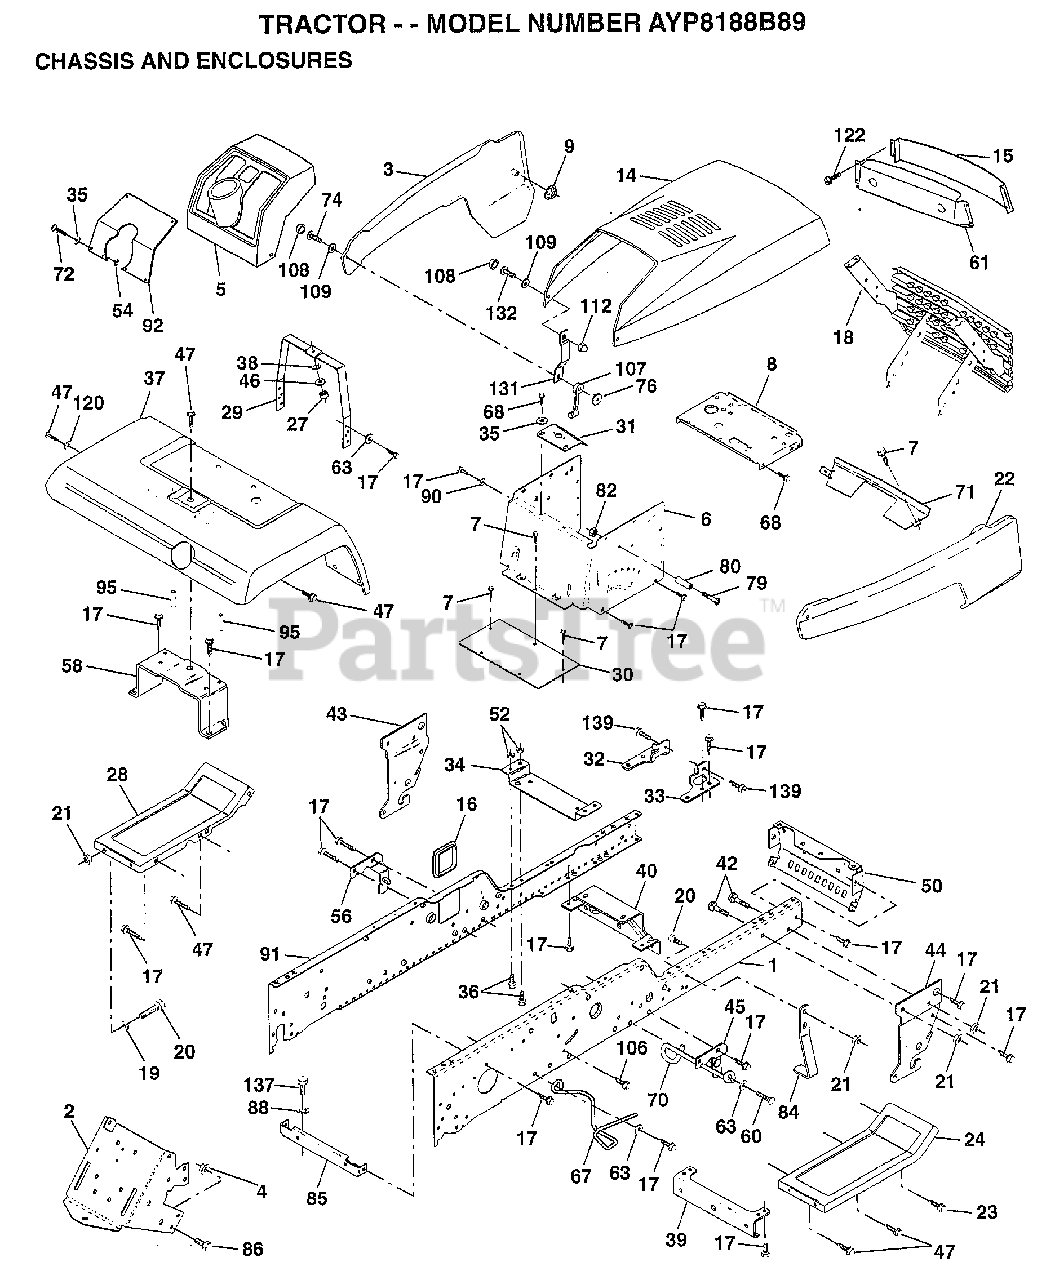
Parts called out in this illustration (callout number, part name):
1	"RAIL,FRAME RH"
2	DRAWBAR GT
3	"PANEL,ASM SIDE LH"
4	NUT.7/16
5	DASHBOARD BLACK
6	DASH LOWER
7	SCREW
8	SUPPORT.DASH.BTRY
9	PAL NUT LT
14	"HOOD ASM.,PNT"
15	LENS.BAR.CLEAR
16	COVER ACCESS
17	SCREW
19	WASHER
20	BOLT
22	PANEL ASM.SIDE RH
23	SCREW GTV
24	FOOTREST.RH.LT/GT
28	FOOTREST.LT.LT/GT
29	DASH.SUPT.YP/HUSQ
30	SADDLE.SCR.6SP
31	BRKT SUPT 1-PC VG
32	BKRT.PIVOT.CHASSIS.RH
33	BKRT.PIVOT.CHASSIS.LH
34	BRACKET.ENG.SUPT.
35	WASHER
36	BOLT
37	"FENDER,RH"
38	LOCKWASHER
39	BRACKET.AXLE.FRT.
40	"BRKT SUPPORT,AXLE"
43	BRACKET.SUS.FT.LH
44	BRACKET.SUS.FT.RH
45	BRACKET.SUSP.RH.
46	WASHER PM
47	SCREW LT
50	"BRKT CHASSIS,FRNT"
56	BRACKET.SUSP.LH.
58	BRKT.ASM.FENDER
60	SCREW
61	BEZEL.ASM.
63	WASHER
67	"GUIDE BELT, T/A"
70	GUIDE.BELT.MID.SP
72	SCREW
74	SCREW
76	WELDNUT
79	SCREW
80	SPACER LT
84	STOP.OVER.CENTER
85	BRACKET.SUPT.TRAN
86	BOLT
88	LOCKWASHER
90	LOCKWASHER
91	"BRKT ASM,GA,WH,FR"
92	"PLATE DASH,SLKSCR"
95	NUT-PUSH YT
107	HOOD LATCH T
108	SNAP CAP LT
109	WASHER LT
112	ACORN NUT RB
120	WASHER HYT
122	SCREW.HEX.WS.HD
131	BKT.SPT.HOOD/PANL
132	SCREW.10-24X3/8.
137	BOLT.FIN.HEX.
139	BOLT.SHOULDER.5/16-18
